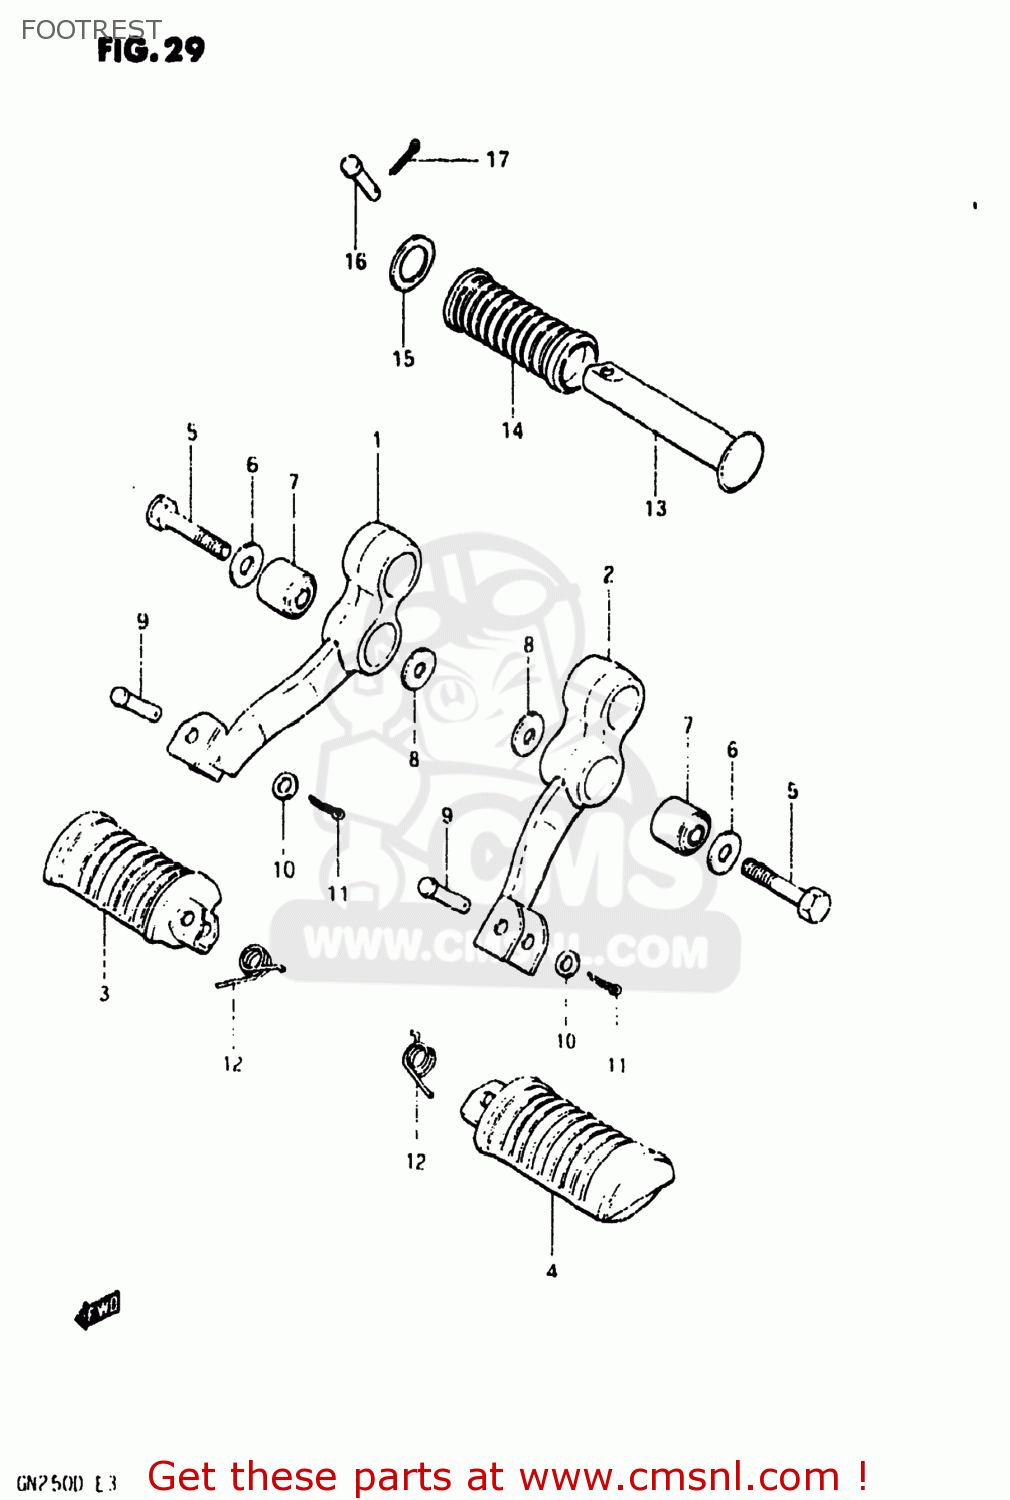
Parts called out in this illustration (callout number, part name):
1	BAR,FRONT FOOTREST
2	BAR,FR FOOTREST,L
3	RUBBER,FRONT FOOTREST
4	FOOTREST
5	BOLT(10X35)
6	WASHER
7	BUSH
8	WASHER
9	PIN
10	WASHER
11	PIN 20X20
12	SPRING
13	BAR,PILLION FOOTREST
14	RUBBER,PILLION FOOTREST
15	WASHER (19.5X32X2)
16	PIN
17	PIN 20X20
